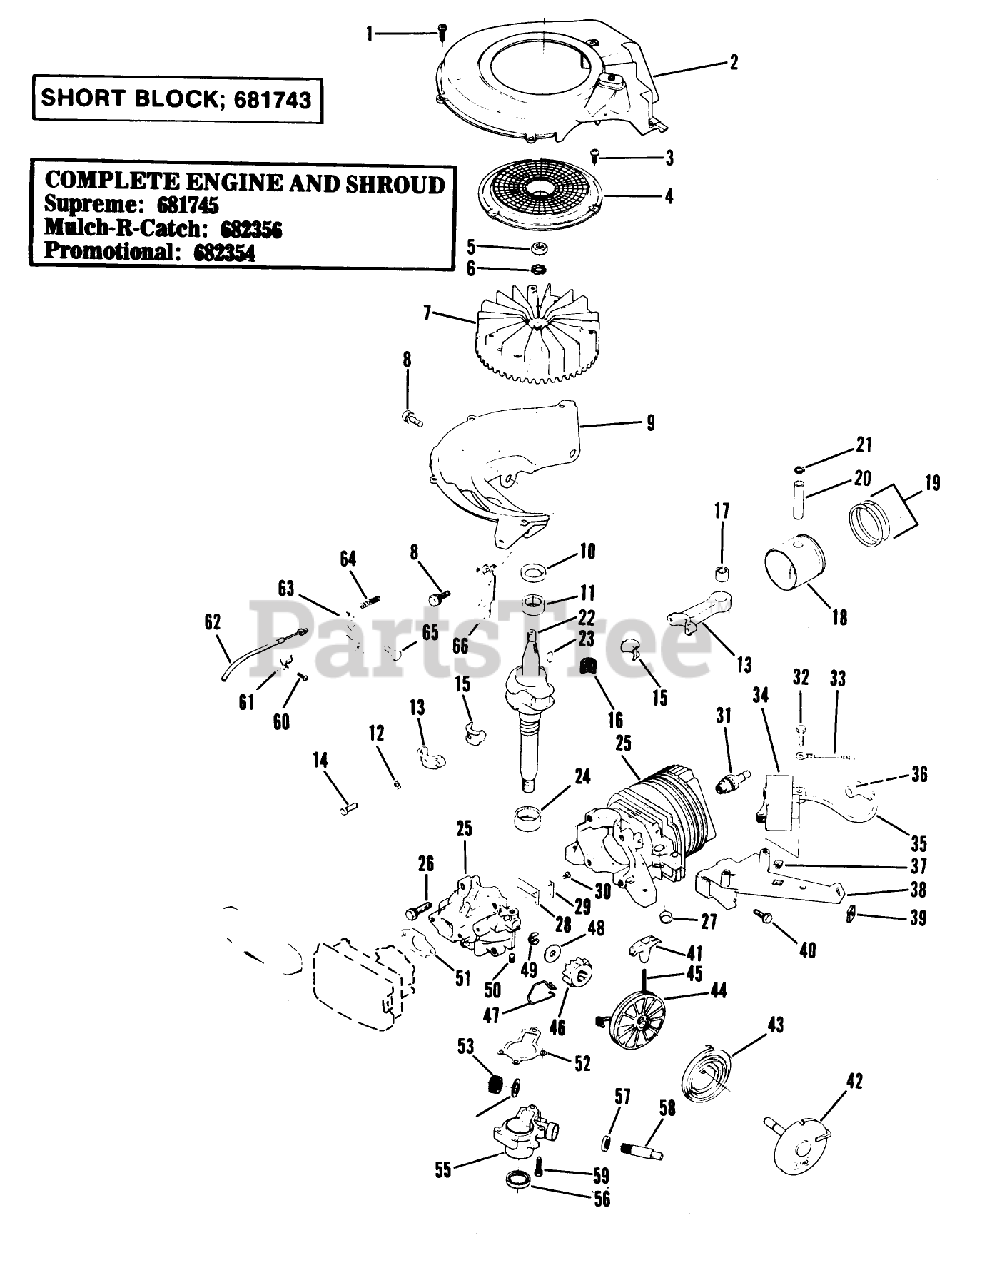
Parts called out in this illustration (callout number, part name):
1	SCREW S
2	AIR BAF&EYELET S
3	SCREW F
8	SCREW-SEMS
9	SHROUD BASE S
11	BEARING V
15	LINER ASM
17	BEARING AY F
21	RING-RETAINING
24	BEARING S
26	SCREW S
27	PLUG-CORE VF
29	PLATE-BACKUP, REED
35	HT LEAD&COVER XEV
37	NUT-CLIP
39	NUT - SPEED S
41	HANDLE STARTER S
43	SPRING S
47	SPRING F
48	WASHER S
50	SET SCREW
51	GASKET CARB S
52	GASKET S
53	GEAR, DR SHAFT S
54	THRUST WASHER
63	LEVER LOCKOUT S
